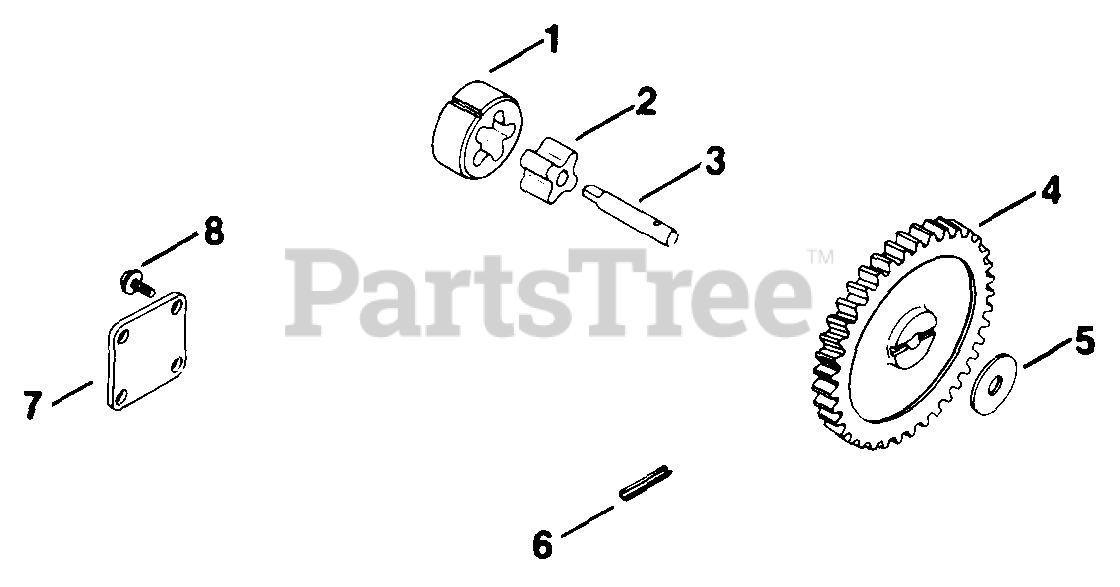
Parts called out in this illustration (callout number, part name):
1	PUMP - USE 52 393 09
2	PUMP - USE 52 393 09
4	GEAR - DISCONTINUED
5	SPACER - (#DSC)
7	COVER - (#DSC)
8	SCREW, WSH HD TAP #10-32X7/16" USE 25 086 101-S
